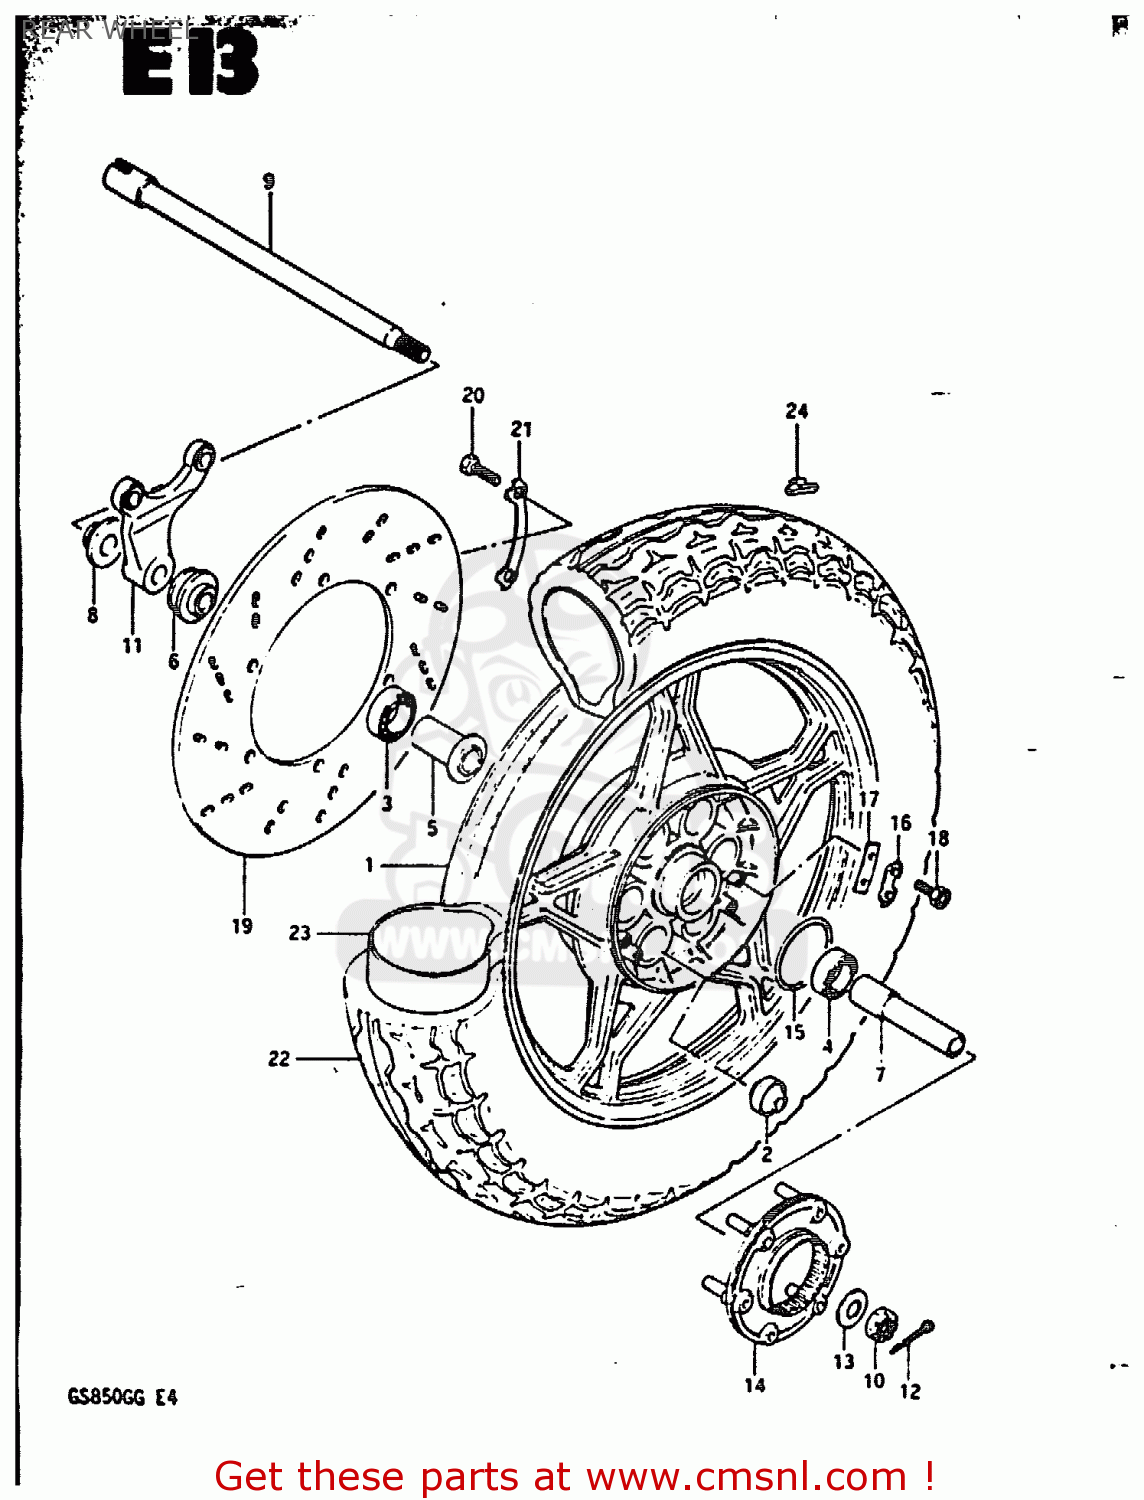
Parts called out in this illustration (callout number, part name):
1	CASTING WHEEL,REAR 2.50
2	BUSH
3	BEARING
4	BEARING
5	SPACER,REAR HUB BEARING
6	SPACER,REAR CALIPER BRACKET
7	SPACER,REAR AXLE,LEFT
8	SPACER,REAR AXLE,RIGHT
9	AXLE,REAR
10	NUT
11	BRACKET,RR,CALIPER
12	PIN,COTTER
13	WASHER (17.5X36X3.2)
14	JOINT ASSY,RR HUB DRIVEN
15	O RING(D:2.1,ID:65)
16	WASHER
17	WASHER,THRUST(T:1.6)
18	BOLT(6X16)
19	DISC,RR BRAKE
20	BOLT(8X25)
21	WASHER
22	TIRE, REAR (4.50H17) BS
23	TUBE ASSY,WHEEL INNER
24	BALANCER,WHEEL
